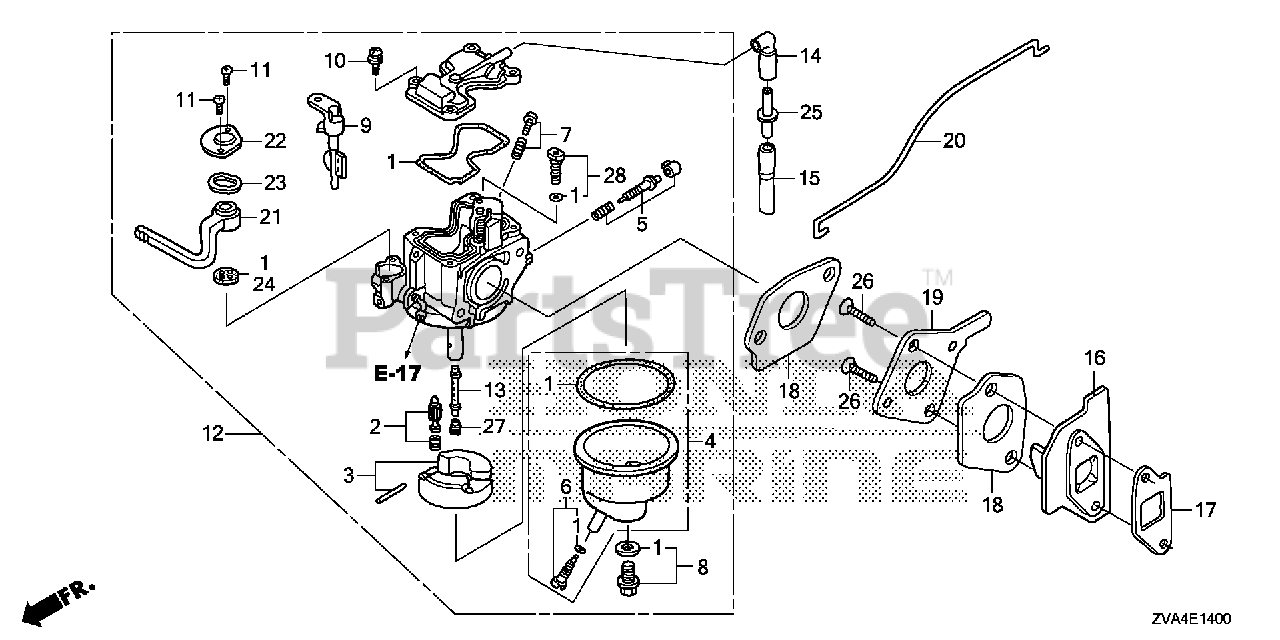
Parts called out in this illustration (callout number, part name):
1	GASKET SET (CARBURETOR NO.)
2	VALVE SET, FLOAT (CARBURETOR NO.) (SEAT NOT INCLUDED)
4	CHAMBER SET, FLOAT
5	SCREW SET (CARBURETOR NO.)
6	SCREW SET, DRAIN
7	SCREW SET (CARBURETOR NO.)
8	SCREW SET (CARBURETOR NO.)
9	LEVER SET, CHOKE
10	SCREW, PAN
11	SCREW, PAN (3X6) (CARBURETOR NO.)
12	CARBURETOR ASSY. (BF33V B)
13	NOZZLE, MAIN (CARBURETOR NO.)
14	TUBE A, AIR VENT
15	TUBE B, AIR VENT
16	INSULATOR, CARBURETOR
17	GASKET, INSULATOR
18	GASKET, CARBURETOR
19	PLATE, CARBURETOR JOINT
20	ROD, CHOKE
21	LEVER, PETCOCK
22	PLATE, LEVER SETTING (CARBURETOR NO.)
23	SPRING, PETCOCK LEVER (CARBURETOR NO.)
24	GASKET, VALVE
25	JOINT, AIR VENT TUBE
26	SCREW, FLAT (5X20)
27	JET, MAIN (#58) Use from Engine SN BF22B D.
27	JET, MAIN (#60)
27	JET, MAIN (#62) (CARBURETOR NO.)
28	JET SET, PILOT (#35)
